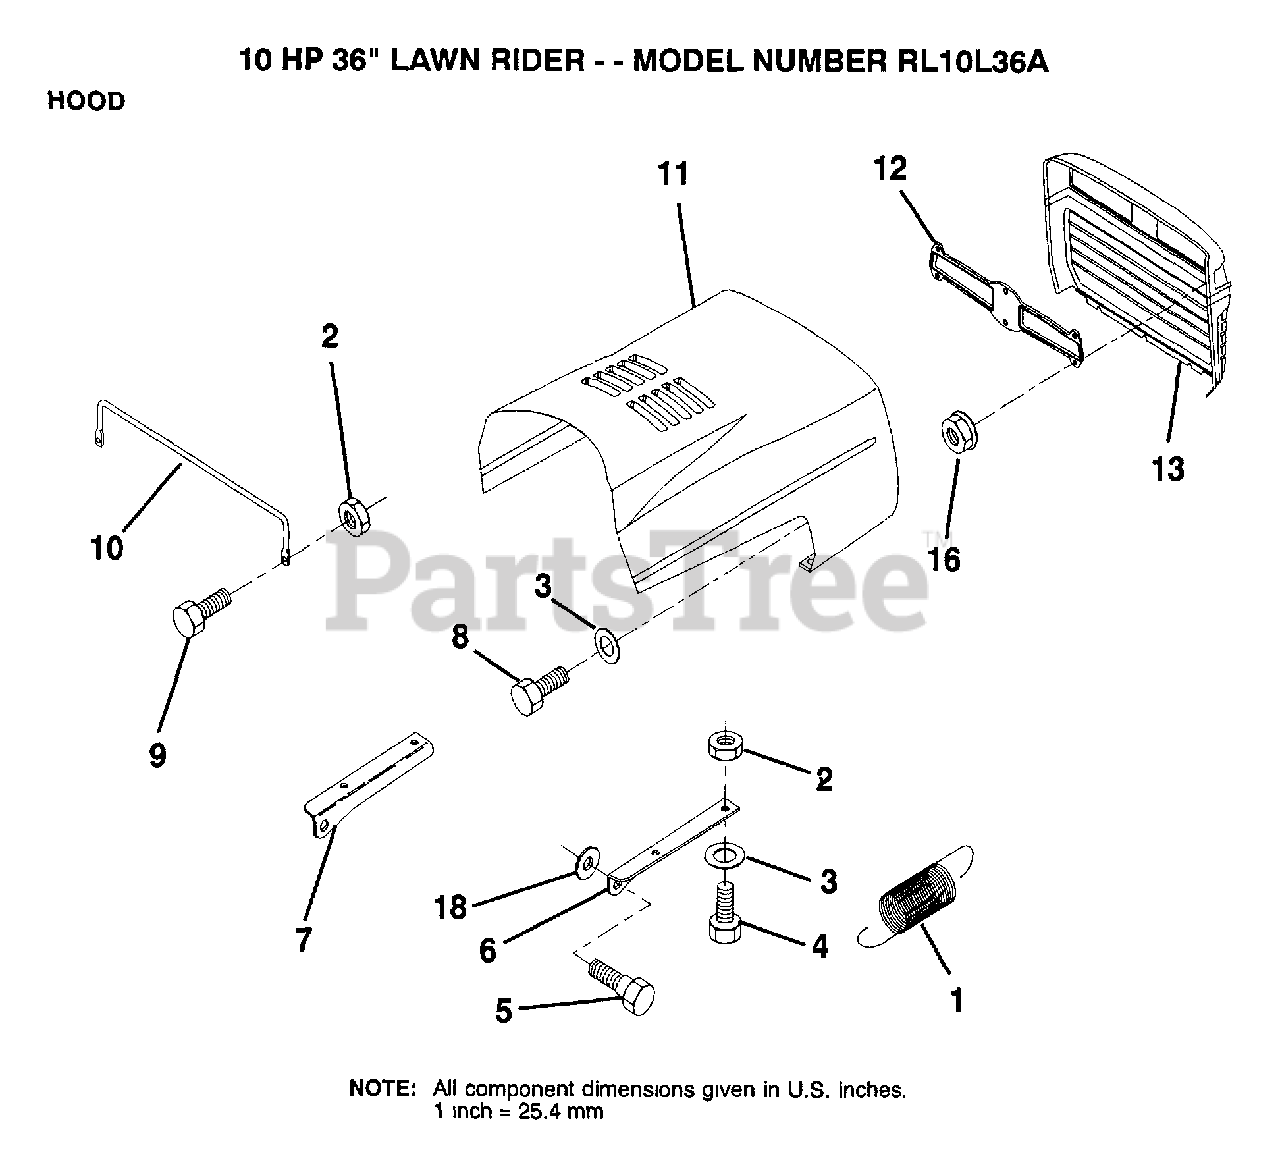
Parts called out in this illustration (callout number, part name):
1	EXT SPRING
2	NUT
3	WASHER
4	BOLT
6	BRKT HOOD RH
7	BRKT HOOD LH
10	"BRACE,HOOD"
11	HOOD
16	NUT
18	WASHER
